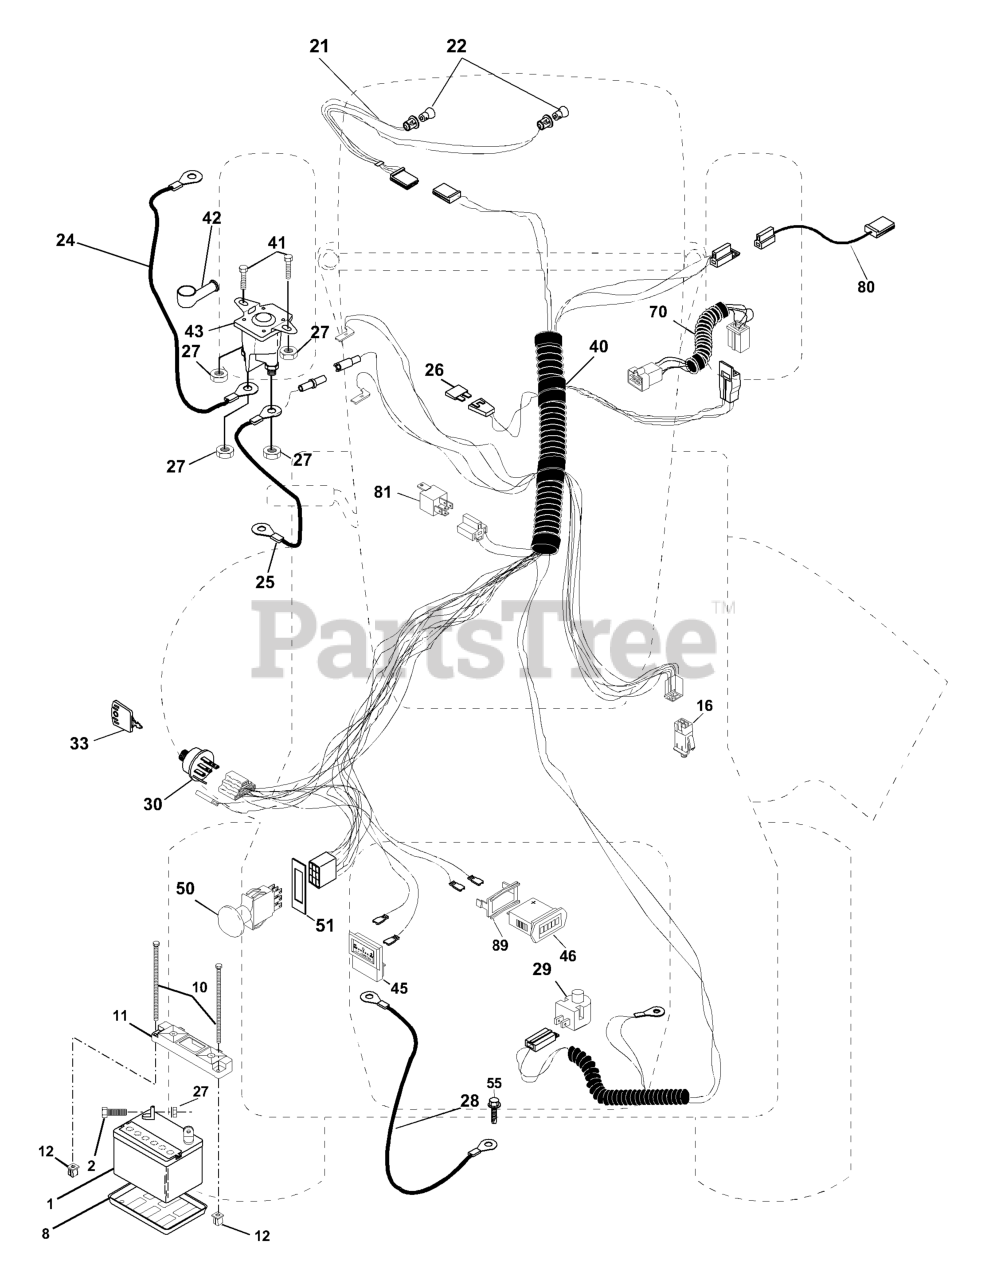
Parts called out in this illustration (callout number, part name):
1	BATTERY 12V .35 AMP
2	BOLT.HEX.1/4.X.3/4.DICHROMATE
8	BATTERY TRAY T
10	BOLT 1/4-20 X 7.5
11	BATTERY HOLDDOWN FRONT MOUNT
12	NUT, PUSH NYLON 1/4" BATTERY
16	SWITCH INTERLOCK
20	NUT
24	BATTERY CABLE GT
25	CABLE BATTERY 6 GA 22" W/16W
26	FUSE 15 AMP
27	NUT
28	CABLE GROUND 6 GA 21" 90T BLK
29	PLUNGER SWITCH (COLOR:OLIVE)
30	SWITCH IGN
33	KEY MLD GEN DELTA
40	HARNESS IGN.
41	BOLT
42	TERMINAL COVER
43	SOLINOID
46	HOUR METER
50	PTO SWITCH
51	FRAME RETAINING RING
55	Screw Thdrol 5/16-18 x 1-1/2 Tyt
70	Harness, Eng.
80	HARNESS, CLUTCH
81	RELAY.ASSY.T
89	BRACKET SNAP-IN HOURMETER
